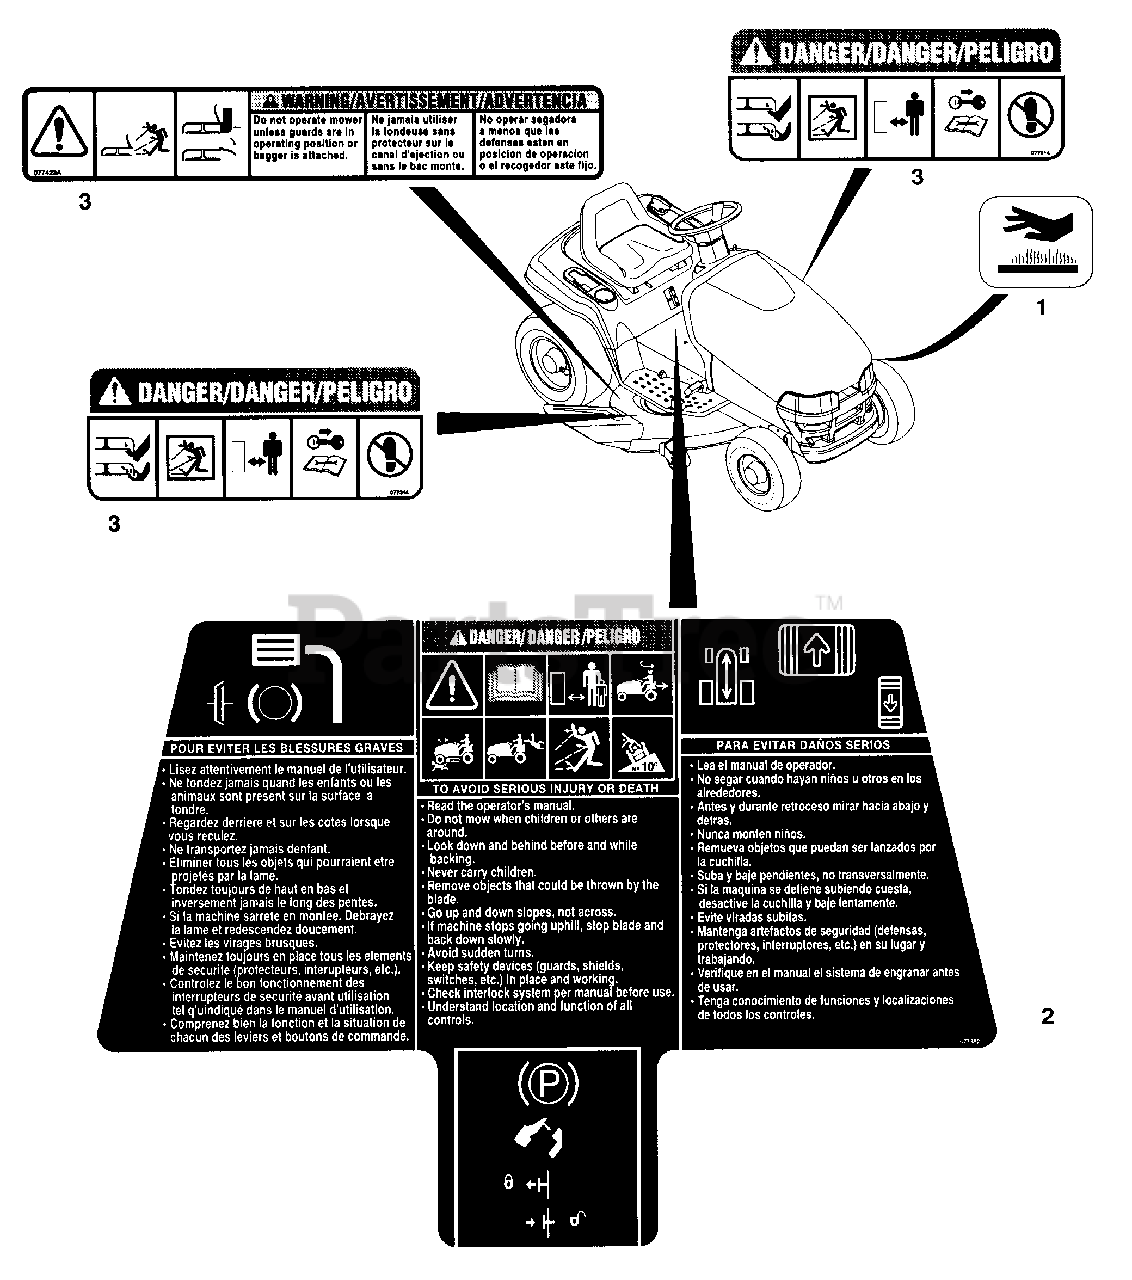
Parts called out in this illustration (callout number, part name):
1	Decal-Hot Surface
2	Decal-Operating Instructions
3	Decal Set-Mower Pan
